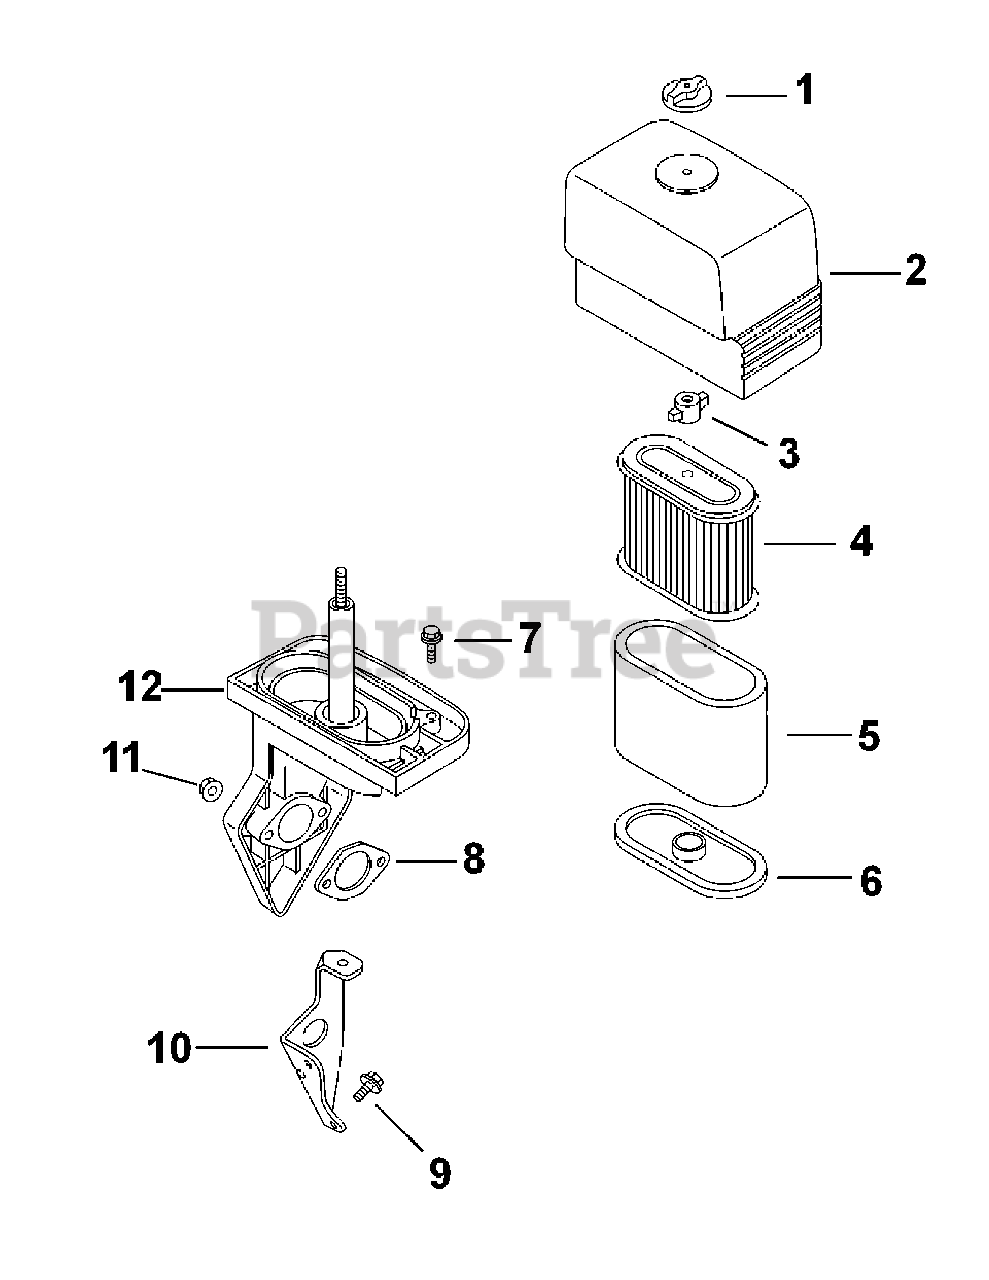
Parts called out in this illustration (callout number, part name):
3	Nut, Wing A/C
5	Pre-cleaner/element
8	Gasket, A/C 8.5
9	Screw, Hex Flange
